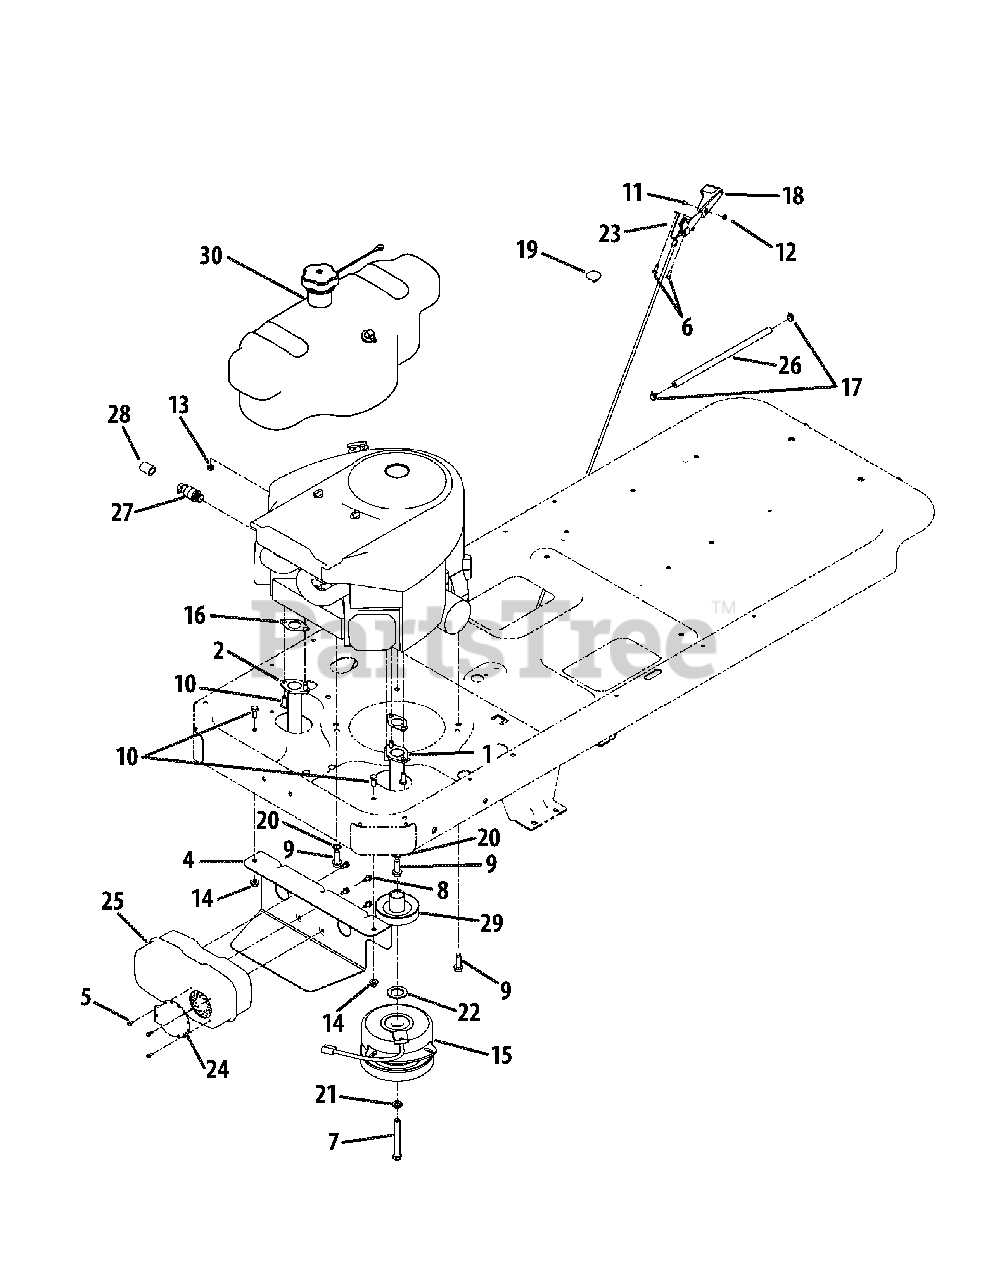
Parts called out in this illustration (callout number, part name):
1	Muffler Exhaust Tube, RH
2	Muffler Exhaust Tube, LH
3	Frame Assembly
4	Muffler Mount Bracket
5	Hex Washer Screw, #8-18 x .500
6	Hex Washer Screw, #12-16 x .50
7	Hex Lock Screw, 7/16-20 x 3.50
8	Hex Washer Screw, 1/4-20 x .500
9	Hex Washer Screw, 3/8-16 x 1.250
10	Hex Screw, 5/16-18 x .75
11	Machine Screw, #8-32 x .375
12	Hex Nut, #8-32
13	Sems Nut, 1/4-20
14	Flange Lock Nut, 5/16-18
15	Electric PTO Clutch
16	Exhaust Gasket
17	Hose Clamp
18	Throttle Control Knob
19	Choke Plug
20	Lock Washer, 3/8
21	Lock Washer, 7/16
22	Flat Washer, 1.031 x 1.620 x .095
23	Throttle/Choke Control Cable
24	Muffler Deflector
25	Muffler
28	Oil Drain Extension Hose
29	PTO Pulley
30	Fuel Tank Assembly
